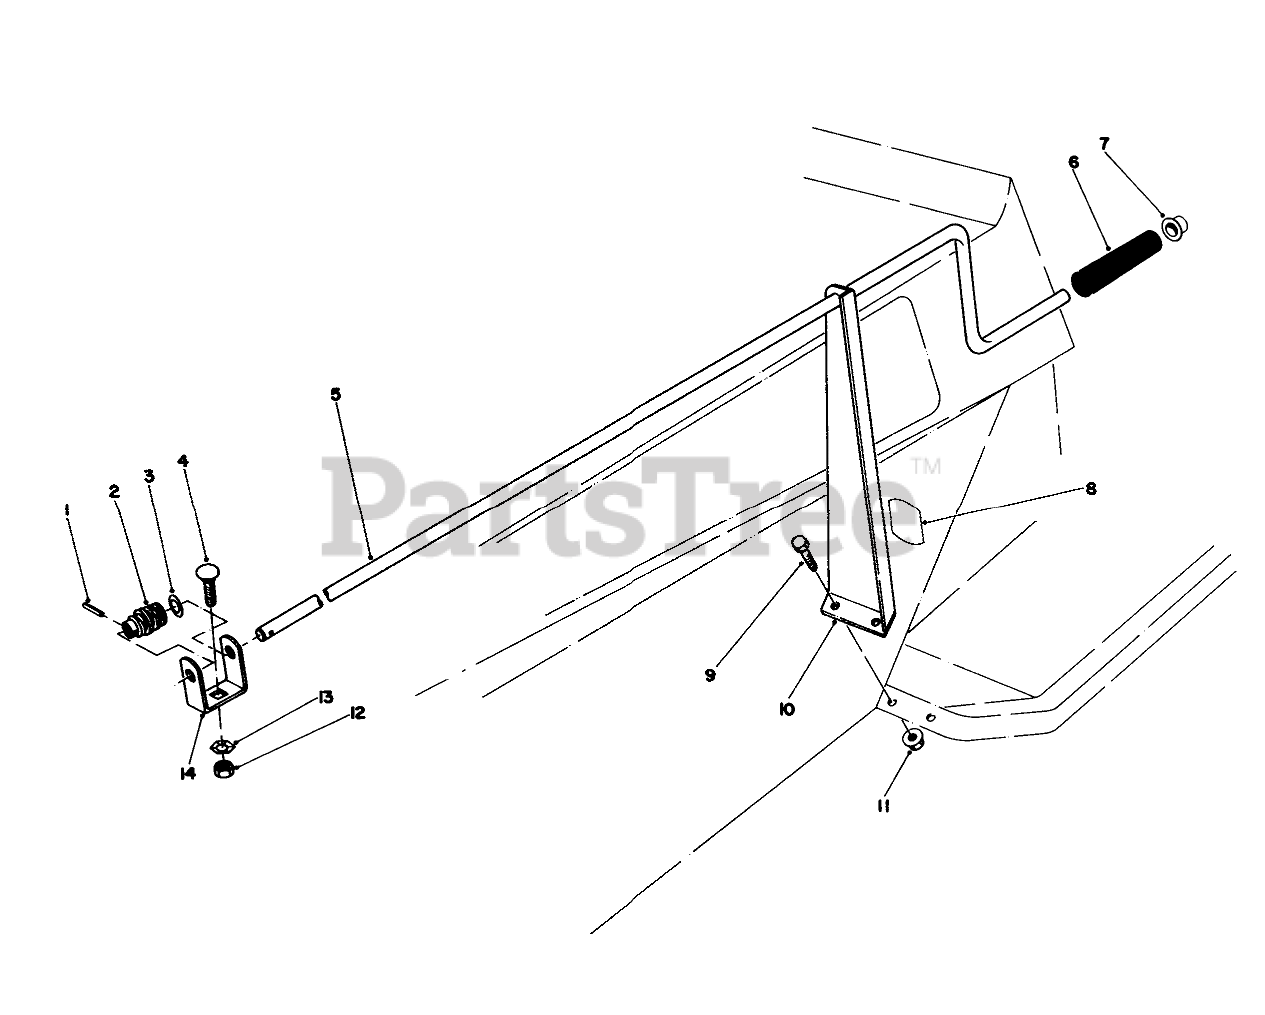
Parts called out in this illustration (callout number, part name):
1	PIN-SPRING
2	GEAR-WORM, CHUTE
3	WASHER-SPRING
4	BOLT-CARR
5	ROD-CHUTE CONTROL
6	GRIP-CONTROL, CHUTE
7	RETAINER-PUSH ON
8	CHUTE DECAL
9	SCREW-HH
10	CHUTE CONT BRKT B
11	NUT-HF
12	NUT-LOCK, NI
13	WASHER-LOCK
14	WORM BRKT B
